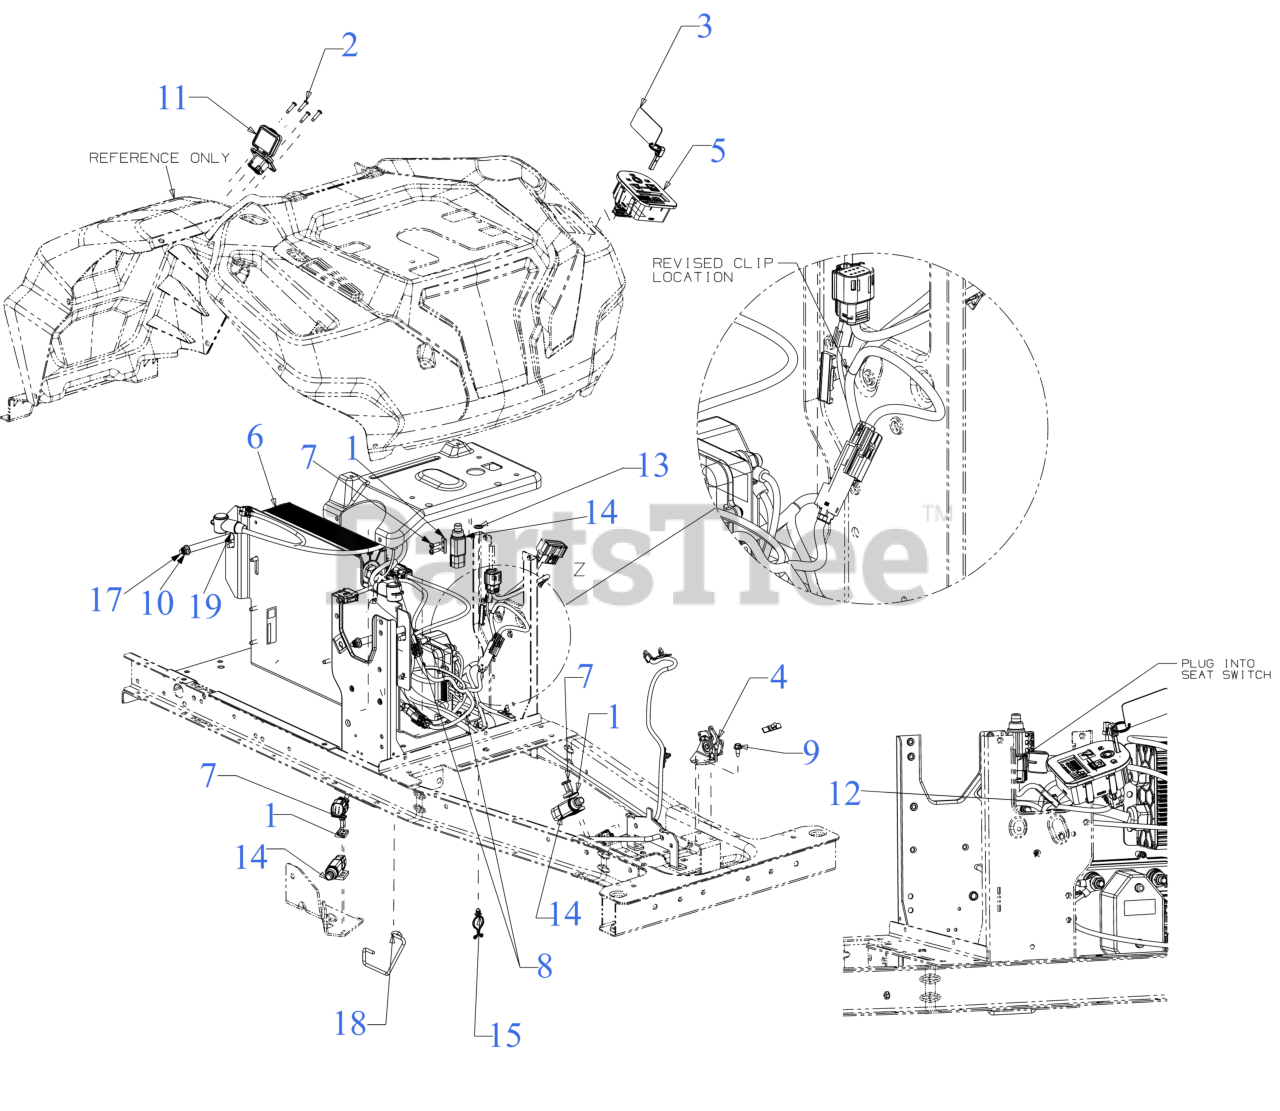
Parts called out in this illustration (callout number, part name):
1	PLATE-SWITCH
2	SCREW, #8-16X.750 PH
3	MAGNETIC KEY
4	THROTTLE SENSOR ASSEMLBLY
5	VCM SWITCH ASSEMBLY
6	Not Serviceable/ Components Only
7	SCREW #10-24X11/16 T-25
8	SCREW M6-1 x .625
9	SCREW 1/4-20X.625
10	FLANGE LOCK NUT 5/16-18
11	CHARGER PORT HARNESS (8-PIN)
12	MAIN HARNESS (VCM/SPDM)
13	PUSH NUT
14	SEALED PLUNGER SWITCH
15	TWIST LOCK CLIP
17	BATTERY ROD 5/16-18
18	DECK CABLE SUPPORT ROD
19	SPACER .322 x .438 x 3.855
